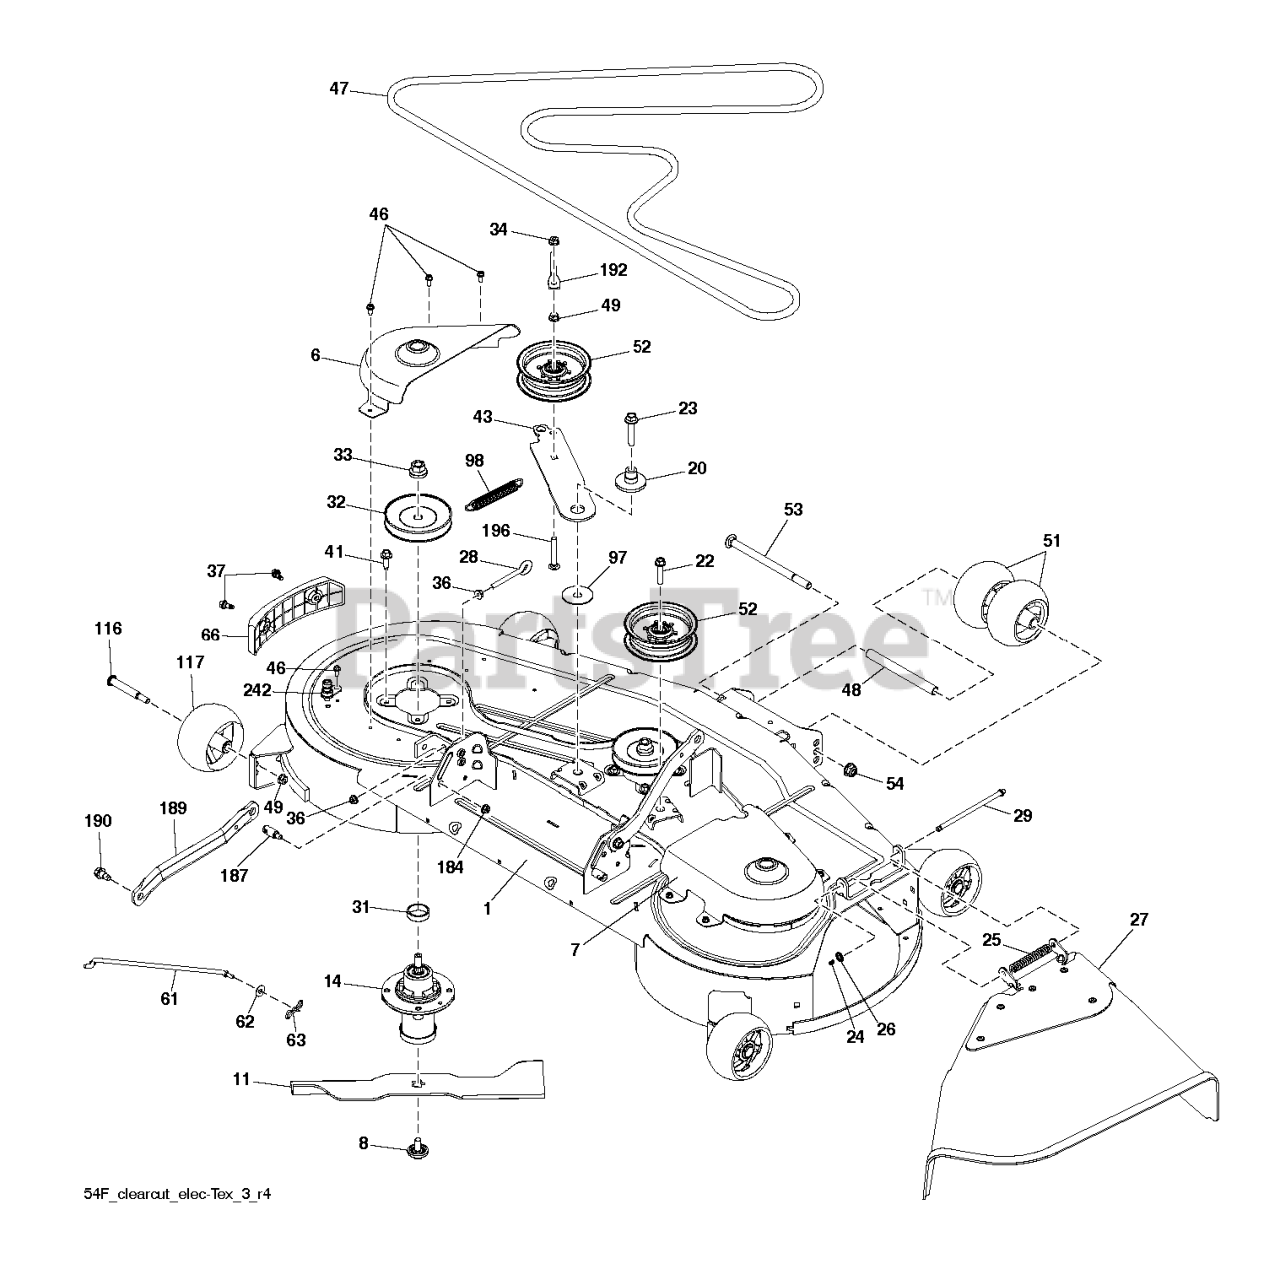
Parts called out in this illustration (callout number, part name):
1	SERVICE KIT KIT.SVC.WELDMENT.5
6	COVER 54 CLEARCUT, LH MANDREL,
7	COVER 54 CLEARCUT RH MANDREL G
8	BOLT.WASHER.ASM.7/16-2
11	BLADE.54CC.HI-LIFT.PZ.165".668
14	MANDREL ASM, CAST IRON
20	SPACER.IDLER.PULLY.HUB
22	BOLT;HEX_3/8-16 X 1.78.CLRZINC
23	SCREW.7/16-14 X 2.125.WASHER
24	CAP-SLEEVE LT
25	SPRING.42.FCS.DEFLECTOR
26	NUT PUSH M
27	DEFLECTOR ASSY 54 CLEARCUT RES
28	GSPW Bolts
31	WASHER.SPACER.MANDREL
32	PULLEY/MANDREL
36	GSPW Hardware
37	SHOULDER BOLT 5/16-18TT
41	BOLT.HEX.WASHR.HED.313-18X1.19
43	ARM IDLER ARM, CLEARCUT 54 BLA
46	SCREW.1/4-20X5/8
47	BELT CLEARCUT 54, TRACTOR DECK
49	NUT LOCK FLG 3/8-16 UNC
51	ROLLER, GAUGE .635 BORN
52	PULLEY.IDLER.2006
54	NUT, 1/2-13 HEX FLG NYLOC ZD
63	PIN.COTTER.5/16.BOW TI
66	BUMPER ASSY 54 CLEARCUT TRIM S
98	SPRING.EXTN.42.FCS.TR.DECK.DRV
117	WHEEL.GAUGE.RALLY
187	STUD.FASTNER.W/ANTI-ROTATE
189	ARM.RFIXED.MOWER.SUSPNSIONX431
190	BOLT.SHOULDER
192	KEEPER.BELT.IDLER.54"T
196	CARRIAGE BOLT 3/8-16 X
242	PORT.WASHOUT
